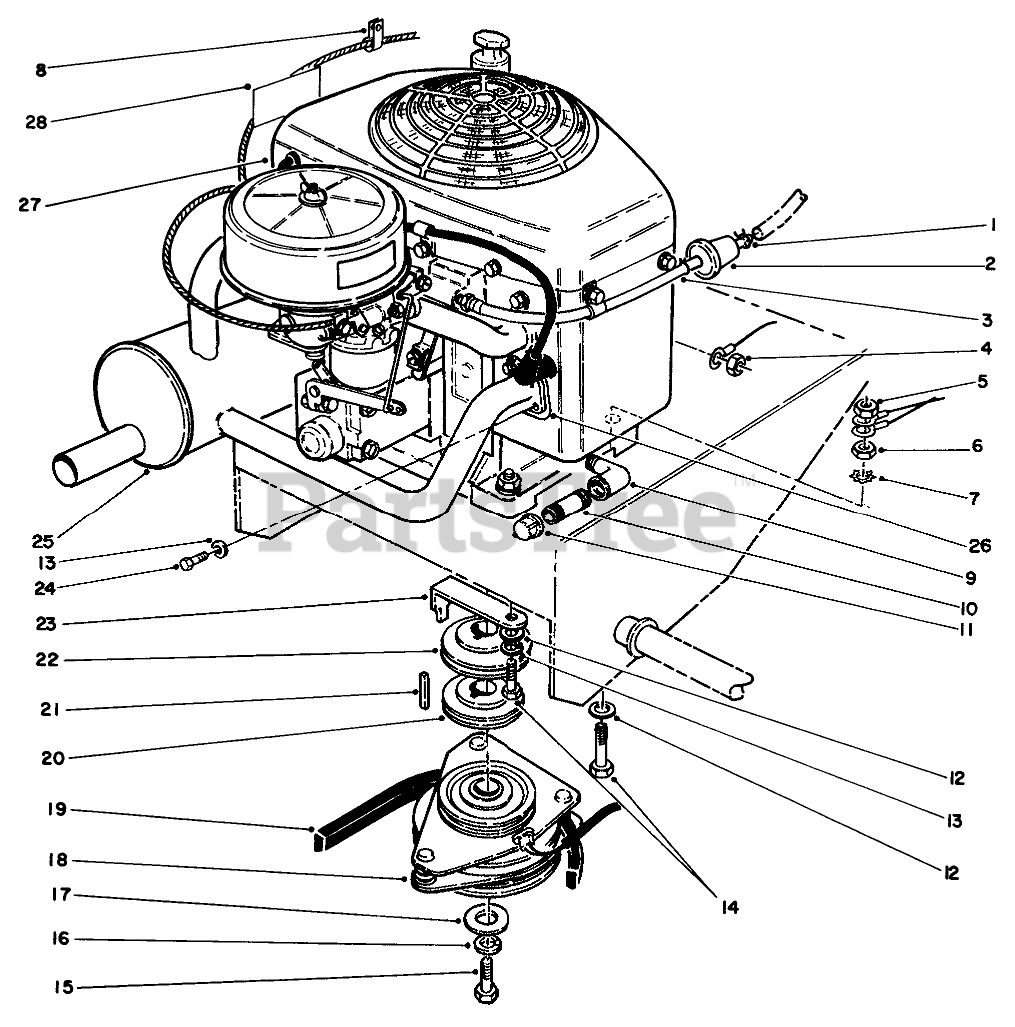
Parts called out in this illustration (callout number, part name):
1	CLAMP-HOSE
2	Fuel-Fllter
3	HOSE-FUEL
4	NUT-KEPS
5	NUT-KEPS
6	NUT-LOCK, CONE
7	WASHER-LOCK
8	CLAMP-R
9	ELBOW-STREET, 90 DEG
10	NIPPLE
11	CAP-PIPE
12	WASHER-PLAIN
13	WASHER-LOCK
14	SCREW-HH
15	SCREW-HH
16	WASHER-LOCK
17	WASHER-CLUTCH
18	CLUTCH/BRAKE
19	V-BELT, DRIVE
20	SHEAVE-LOWER HALF
21	KEY-SQUARE
22	SHEAVE-UPPER HALF
23	Retainer-Clutch
24	SCREW-HSH
25	MUFFLER
26	EXHAUST GASKET F/W ENG.
28	DECAL-SURFACE, HOT
